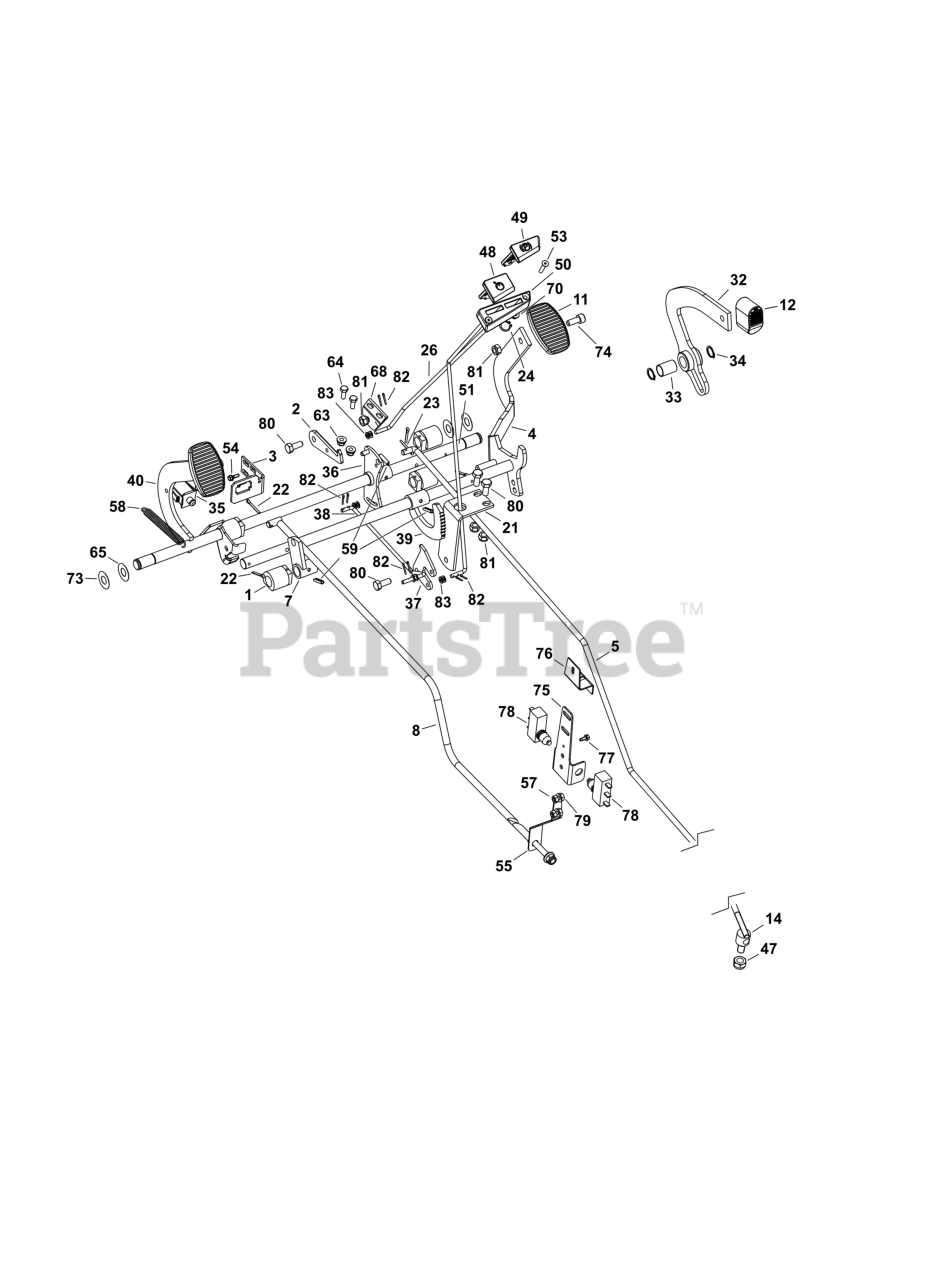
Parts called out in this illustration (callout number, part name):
3	BRACKET, Switch
5	ROD, Brake
11	PAD, Rubber
12	PAD, Foot
32	PEDAL, Foot
40	SHAFT, Brake
78	MICROSWITCH
